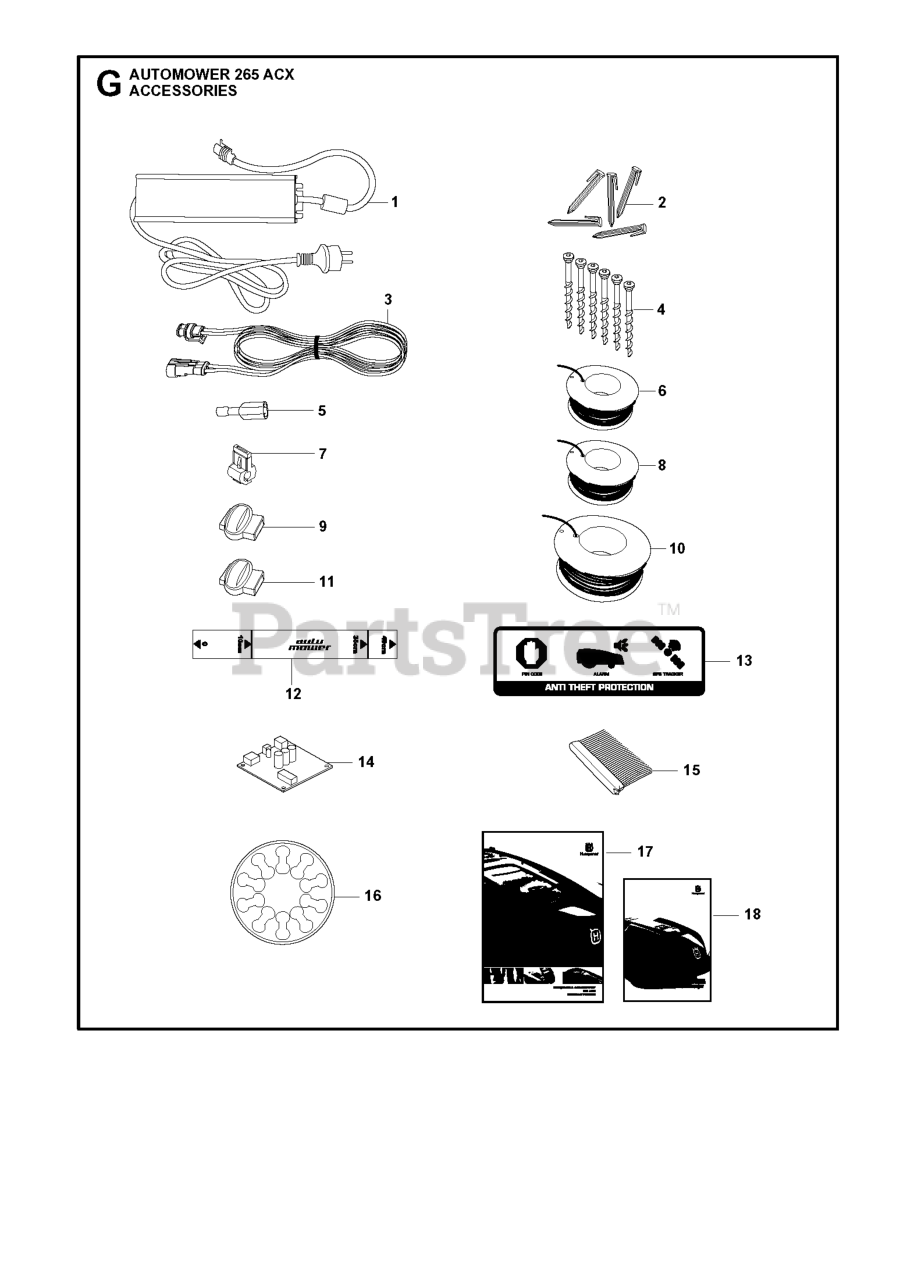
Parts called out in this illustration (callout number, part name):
2	STAPLES (100 CT BAG)
2	STAPLE 100 PCS, BLISTER
4	SCREW KIT CS
4	SCREW 3 PCS, BLISTER PACK
6	LOOP WIRE 150M
6	WIRE 150M, BLISTER
7	BRAKER
7	CONNECTOR 5 PCS, BLISTER
8	LOOP WIRE 250M
9	SPLICE KIT
9	COUPLER SPLICER, 5 PCS,
10	WIRE 500M
11	SPLICE CONNECTOR 50 PCS/PK
14	CIRCUIT BOARD ASSY PCBA GEN BO
15	BRUSH KIT
